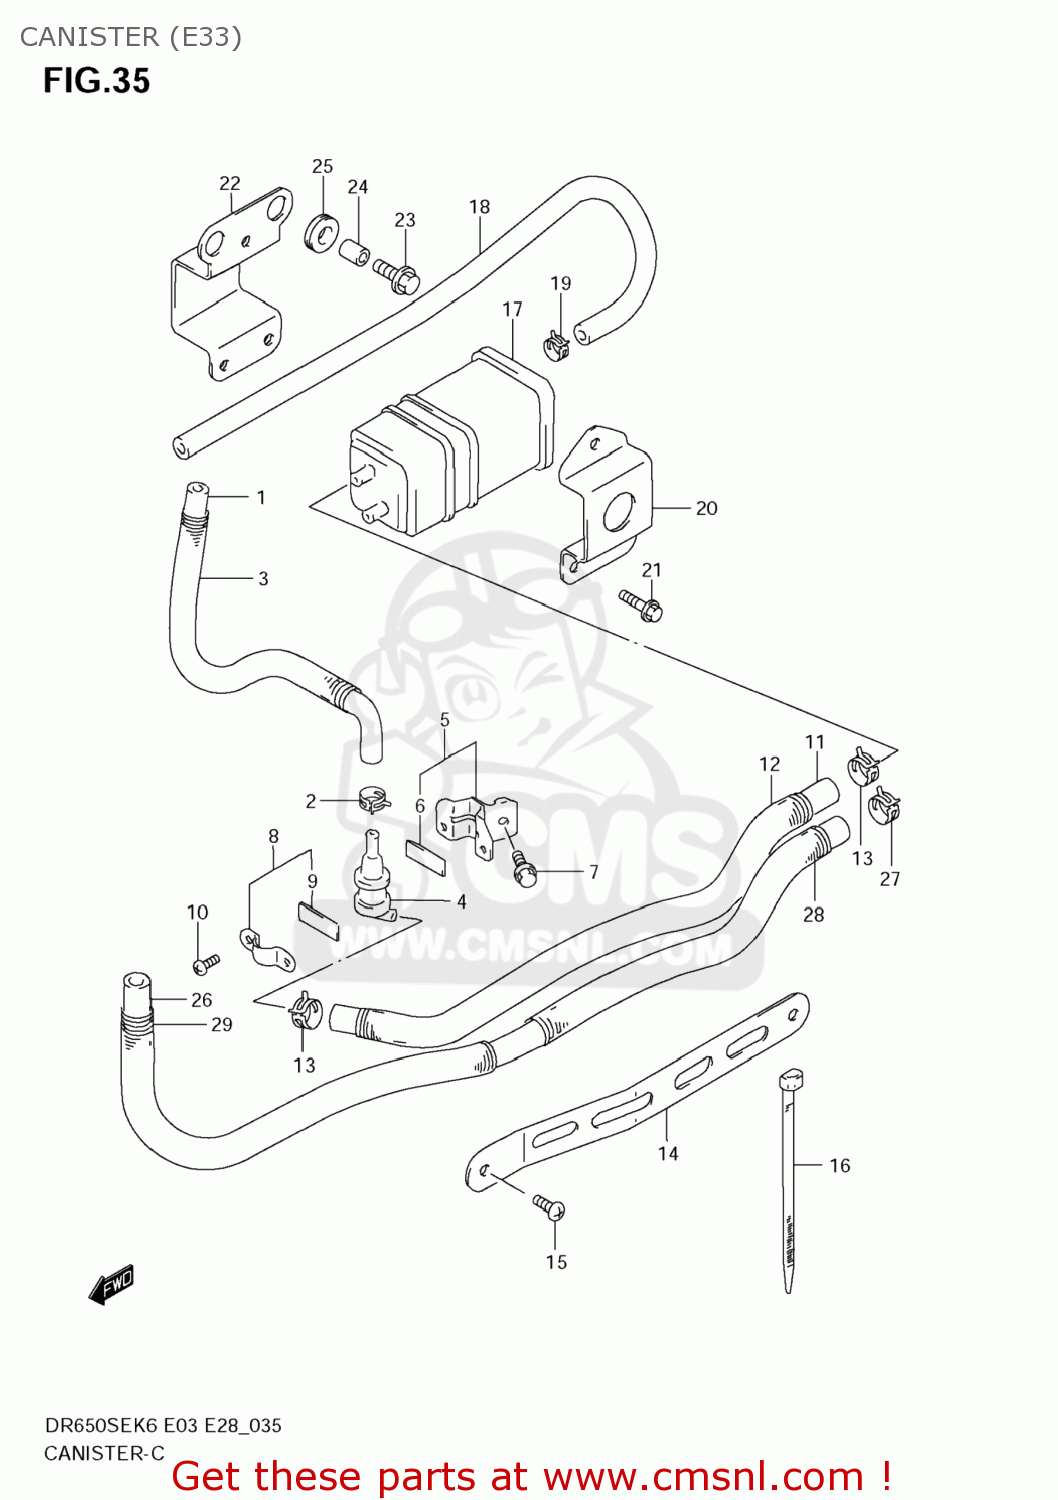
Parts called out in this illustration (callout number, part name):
1	HOSE,TANK & VALVE CHARGE
2	CLIP
3	SPRING
4	VALVE,FUEL TANK BREATHER
5	PLATE,BREATHER VALVE
6	CUSHION
7	BOLT
8	PLATE,FUEL TANK BREATHER NO.2
9	CUSHION
10	SCREW
11	HOSE(5.4X11.4X600)
12	SPRING
13	CLIP
14	PLATE,CANISTER HOSE
15	SCREW
16	CLAMP(L:125)
17	CANISTER ASSY,CHARCOAL
18	HOSE(7X12X600)
19	CLIP
20	PLATE,CSTR UPR
21	BOLT
22	PLATE,CSTR LWR
23	BOLT(6X20)
24	SPACER(6.5X10X9.4)
25	CUSHION
26	HOSE(5.4X11.4X2000)
27	CLIP
28	SPRING
29	SPRING
